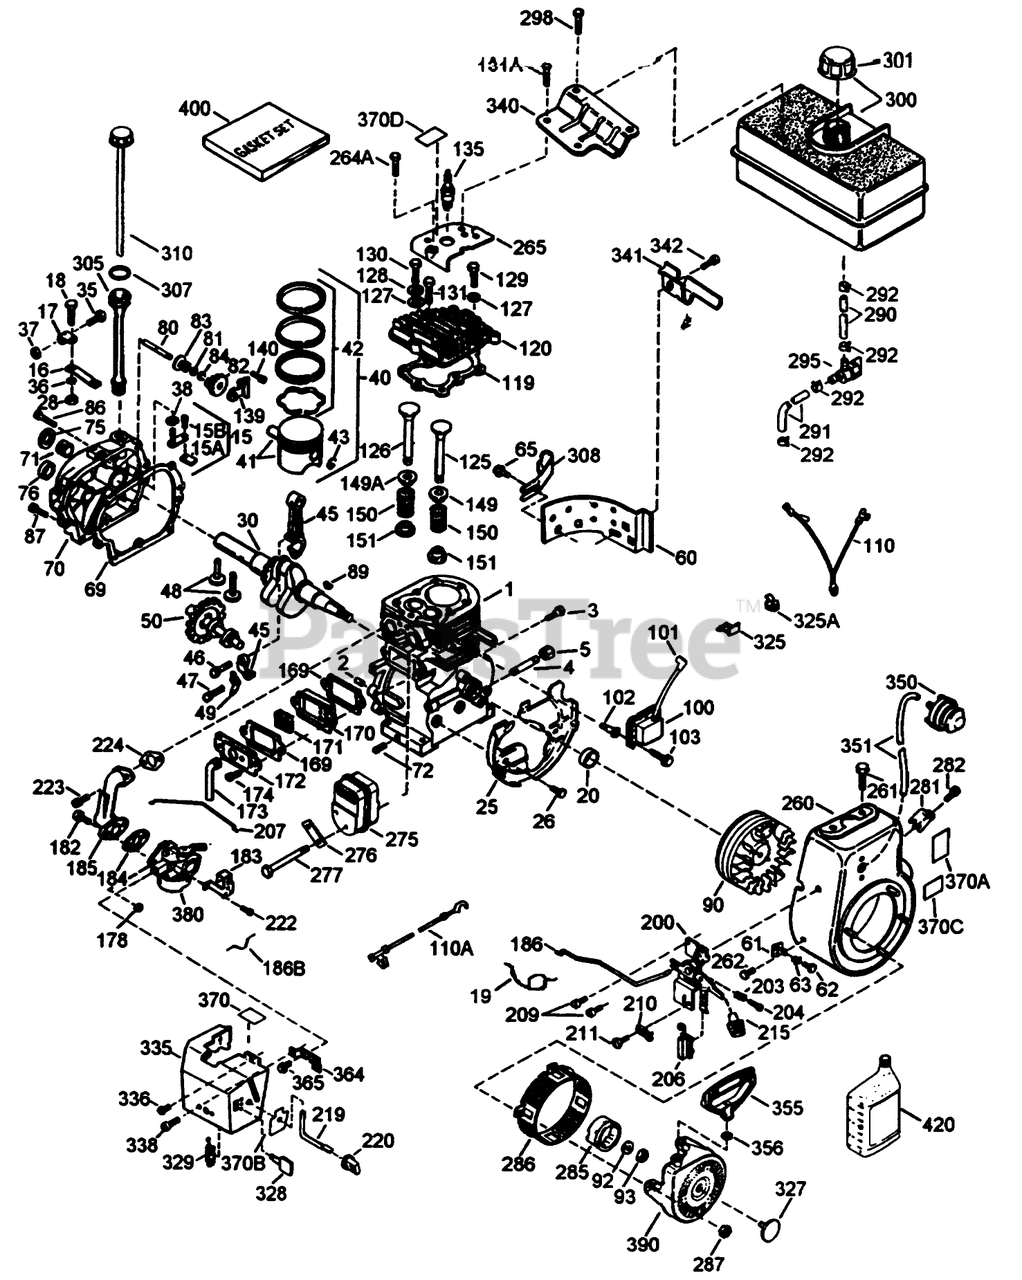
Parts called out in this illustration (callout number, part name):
1	Cylinder (Incl. ref. #2 20)
2	Pin-Dowel
3	Screw (1/4-20x1/2)
4	Nipple-Pipe
5	Cap-Pipe
15	Rod, Governor (Incl. Nos.62 63)
15A	Yoke-Governor
15B	Screw (6-40x5/16)
16	Lever-Governor
17	Clamp-Lever, Governor
18	Screw
19	Spring-Throttle
20	Seal-Oil
25	Baffle-Housing, Blower
26	Screw (1/4-20x19/32)
28	Nut-Lock
30	Crankshaft
35	Screw
36	Washer-Lock
37	Nut-Lock
38	Ring-Retaining
40	Piston, Pin Ring Assy. Std.(Includes ref. #41, 42 43)
41	Piston Pin Assembly Standard (Includes ref. #43)
42	Ring Set (STD)
43	Retaining Ring-Piston Pin
45	Rod Assembly-Connecting (Incl. ref. #46, 47 49)
46	Bolt-Rod
47	Bolt-Rod
48	Lifter-Valve
49	Dipper-Oil
50	Camshaft (MCR)
60	Extension-Housing, Blower
61	Bracket
62	Screw (8-32 x 3/8)
63	Grommet
65	Screw
69	Gasket-Cover, Cylinder
70	Cover-Cylinder (Includes 71, 75, 80)
71	2025A77 WIZARD ROTA
75	Seal-Oil
80	Shaft-Governor
81	Washer-Flat
82	Gear Assy., Governor (Incl. Ref. #45)
83	Spool-Governor
84	Ring-Retaining
86	Screw (1/4-20x1-3/16)
87	Screw (1/4-20x1-11/16)
89	Key-Flywheel
90	Flywheel ASM
92	Washer-Belleville
93	Nut-Flywheel
100	Solid State ASM
101	Cover-Spark Plug
103	Screw (T-15, 10-24 x 15/16)
110	Ground Wire
119	Gasket-Head, Cylinder
120	Head-Cylinder
125	Valve, Exhaust (Standard)(Incl. No. 9)
126	Valve, Intake (Std.) (Incl. Ref. #58)
127	Washer-Flat
128	Washer-Belleville
129	Screw (5/16-18x1-25/32)
130	Screw (5/16-18x1-1/2)
131	Screw (5/16-18 X 2)
131A	Screw
135	Spark Plug-Resistor (R J19 L M)
139	Bracket-Gear, Governor
140	Screw (10-24x1/2)
149	Cap-Spring, Valve
149A	51106 GILSON ROTARY
150	Spring-Valve
151	Keeper-Spring, Valve
169	Gasket-Cover, Valve
170	Body-Breather
171	Element-Breather
172	Cover-Valve
173	Tube-Breather
174	Screw
178	Nut and Lock Washer (1/4-28)
182	Screw (1/4-28x1)
183	Bracket-Choke
184	Gasket-Carburetor To Intake Pipe
185	Pipe-Intake
186	Link-Governor
186B	Spring-Choke
200	Bracket-Control (Includes 19, 203, 204, 206)
203	Spring-Compression
204	Screw
206	Terminal
207	Link-Throttle
209	Screw (10-32 x 1/2)
215	Knob-Control
219	Rod-Choke
220	Knob-Control
222	Screw (10-32 x 1/2)
223	Screw (T-30, 5/16-18x1-3/32)
224	Gasket-Pipe, Intake
260	Housing-Blower
261	Screw (5/16-18x3/4)
262	Screw
264A	Screw (1/2-20x5/8)
265	Cover-Cylinder Head
275	Muffler
276	62513 SNWTHWR W/284
277	Screw (5/16-18x4-3/16)
281	Screw
282	Screw (8-32 x 3/8)
285	Cup-Starter
286	Screen-Starter
287	Nut and Lock Washer (1/4-28)
290	Line-Fuel (8.62)
291	Line-Fuel
292	Clamp-Line, Fuel
295	Valve-Shut Off, Fuel
298	Screw (1/4-15x7/8)
300	Tank-Fuel (Includes 292, 301)
301	Cap-Fuel
305	Tube-Fill, Oil
306	O-Ring
308	Clip-Tube, Fill
310	Gauge Oil ASM
314	Screw (1/4-20 x 3/4)
316	Coil-Alternator, 18 Watt (Includes 323)
323	Terminal
325	Clip-Wire
327	Plug Starter
335	Cover-Carburetor
336	Screw (10-32x1/2)
338	Screw (10-32 x 3/8)
340	Bracket-Tank, Fuel
341	Bracket-Tank, Fuel (Black)
342	Screw (1/4-20x19/32)
350	Primer-Asm
351	Line-Primer
355	Handle-Starter, Mitten Grip
364	Bracket-Carburetor
365	Screw (8-32x27/64)
380	Screw-Hex Washer Hd.
390	Rewind Starter
400	Gasket Set
421	Oil-Engine (SAE 5W30)
